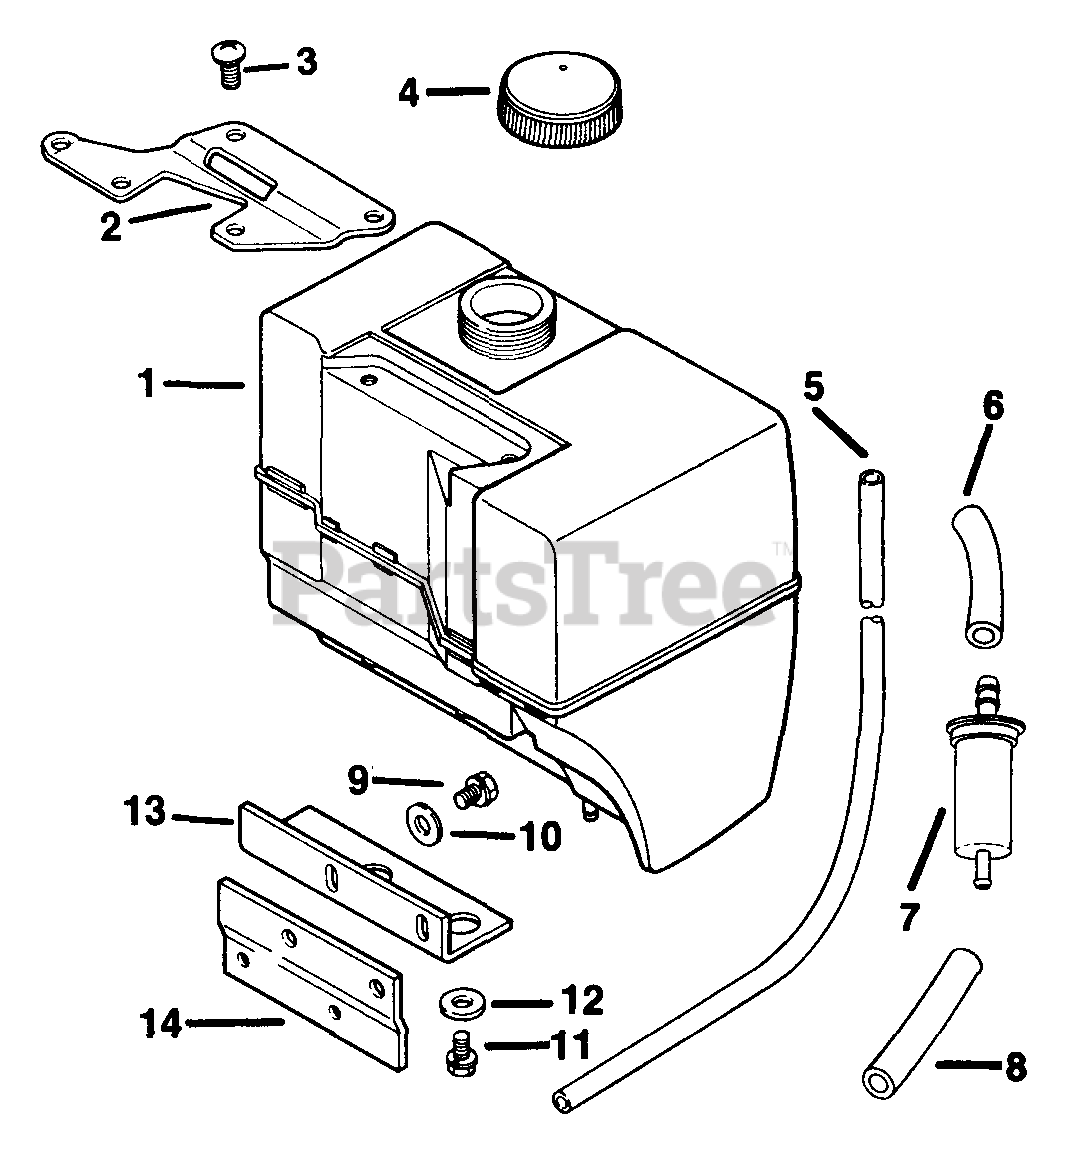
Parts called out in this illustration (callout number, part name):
1	KIT - USE 41 721 03
3	SCREW - USE 47 086 08
4	CAP - USE 41 173 06
9	SCREW, SEMS 1/4-20X5/8" USE 25 086 539-S
10	WASHER, FLAT 1/4"
11	SCREW, SEMS 1/4-20X5/8" USE 25 086 539-S
12	WASHER, PLAIN 1/4"
13	BRACKET - DISCONTINUED
